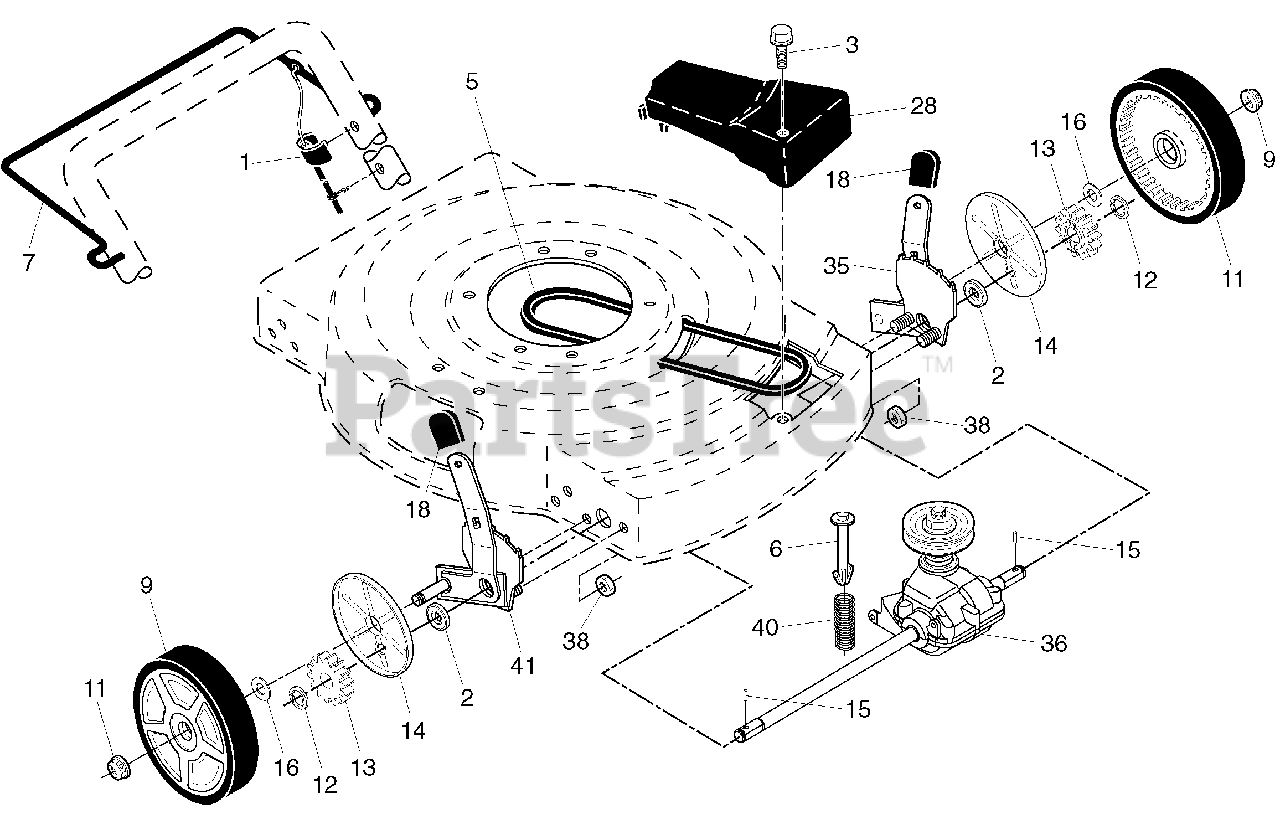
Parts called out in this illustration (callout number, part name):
1	Drive Control Cable Assembly
2	Bearing, Wheel Adjuster
3	Pan Head Tapping Screw #10-24 x 2-3/4
6	Spring Retainer
7	Control Bar, Drive
9	Locknut, Hex
11	Wheel & Tire Assembly
12	E-Ring
13	Pinion
14	Dust Cover
15	Pawl, Drive
16	Washer
18	Selector Knob
28	Drive Cover
35	Kit, Wheel Adjuster, LH
36	Gear Case Assembly, Complete
38	Locknut, Hex 1/4-20
40	Spring
41	Kit, Wheel Adjuster, RH
